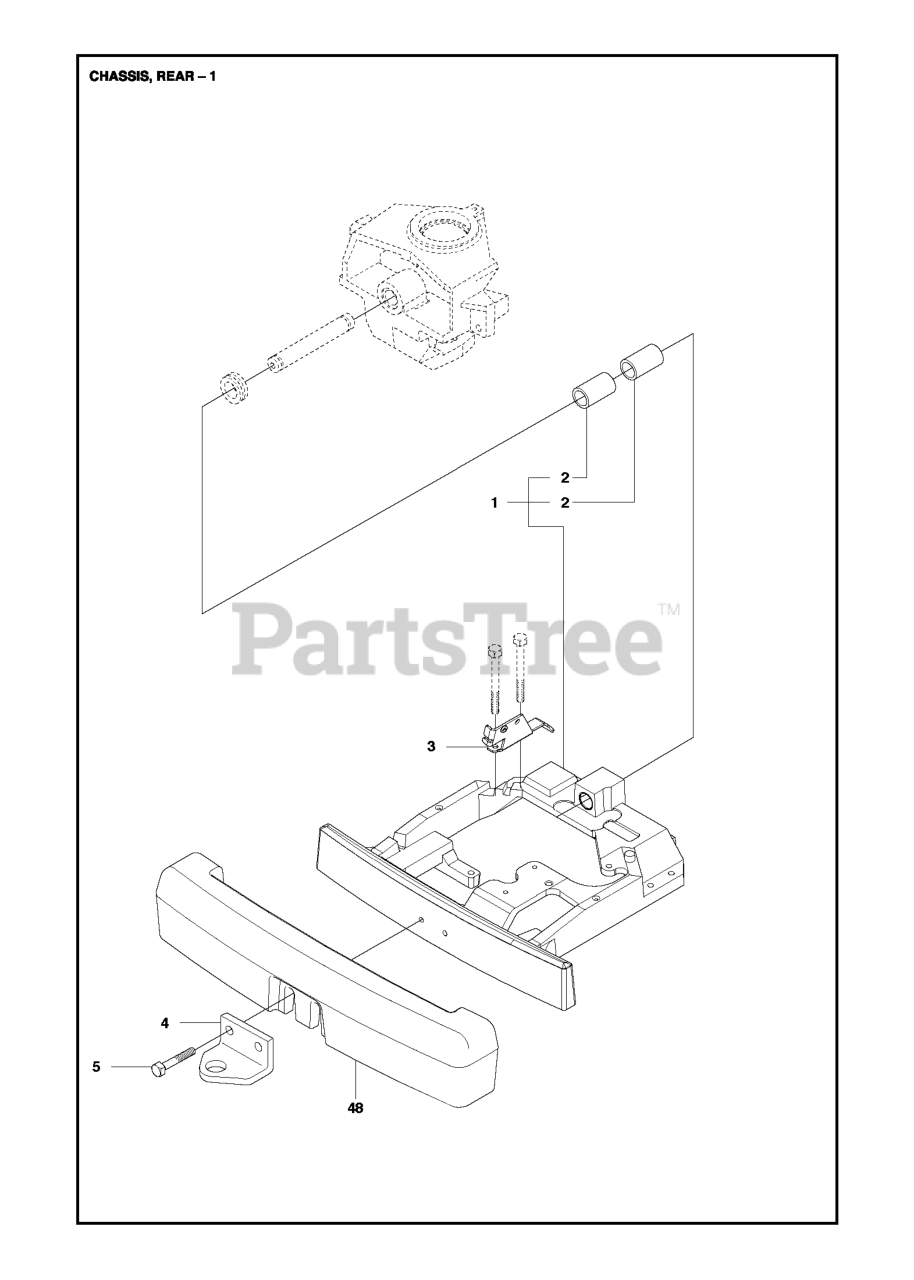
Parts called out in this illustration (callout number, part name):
1	BRACKET
5	Screw M10x25
5	REPL BY 725 25 00-71
48	COUNTERWEIGHT
